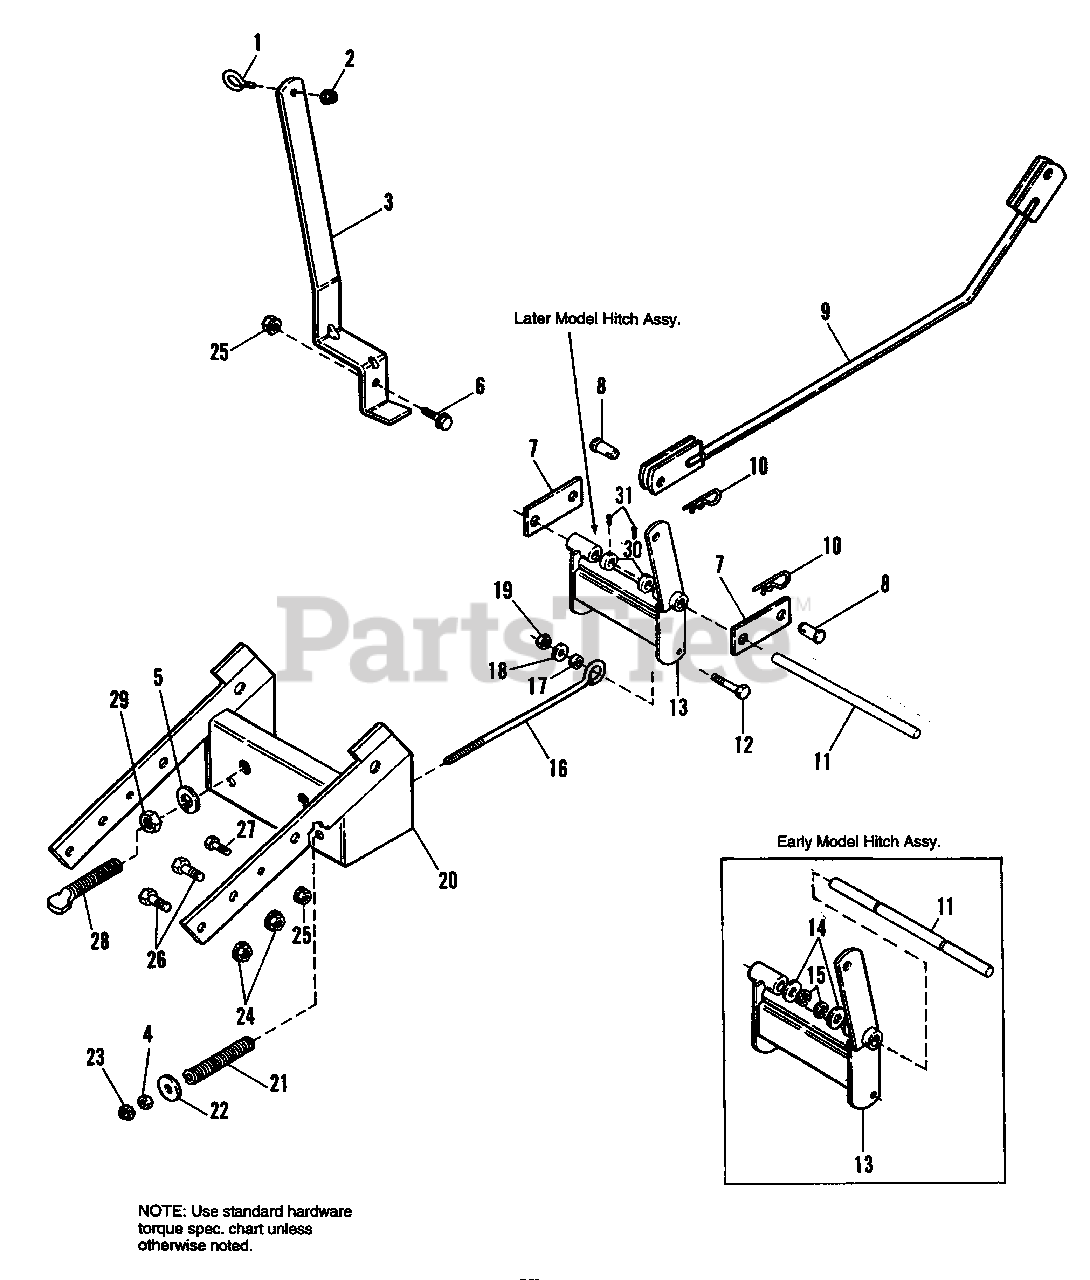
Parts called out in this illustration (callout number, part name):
2	NUT, Hex, Lock 1/4-20
3	SUPPORT, Control Rod
4	NUT, Hex, 3/8-16
5	LOCKWASHER, 3/4 Std.
6	SCREW, Hex, Flange Whizlock, 3/8-16 x 1-1/4
8	PIN, Clevis
9	LIFT ROD ASSY.
10	CLIP, Spring
11	SHAFT, Inner
12	CAPSCREW, Hex Hd., 5/8-11 x 2
13	HITCH ASSY.
14	WASHER, Plain, 41/64 x 1-1/4 x 1/16
15	RING, Retaining "E" 5/8
18	WASHER, Plain, 41/64 x 1-3/4 x 1/8
19	NUT, Hex, Centerlock, 5/8-11
20	HITCH ASSY., Blower
21	SPRING, Compression
22	WASHER, 13/32 x 1-1/4 x 1/4
23	NUT, Jam, Hex, 3/8-16
24	NUT, Hex, Flange, Whizlock, 7/16-14
25	NUT, Hex, Flange, Whizlock, 3/8-16
26	CAPSCREW, Hex Hd., 7/16-14 x 1
27	CAPSCREW, Hex Hd., 3/8-16 x 1
29	NUT, Hex, 3/4-10
30	SET-COLLAR
31	SET-SCREW, Sq. Hd. cup point, 5/16-18 x 1/2
